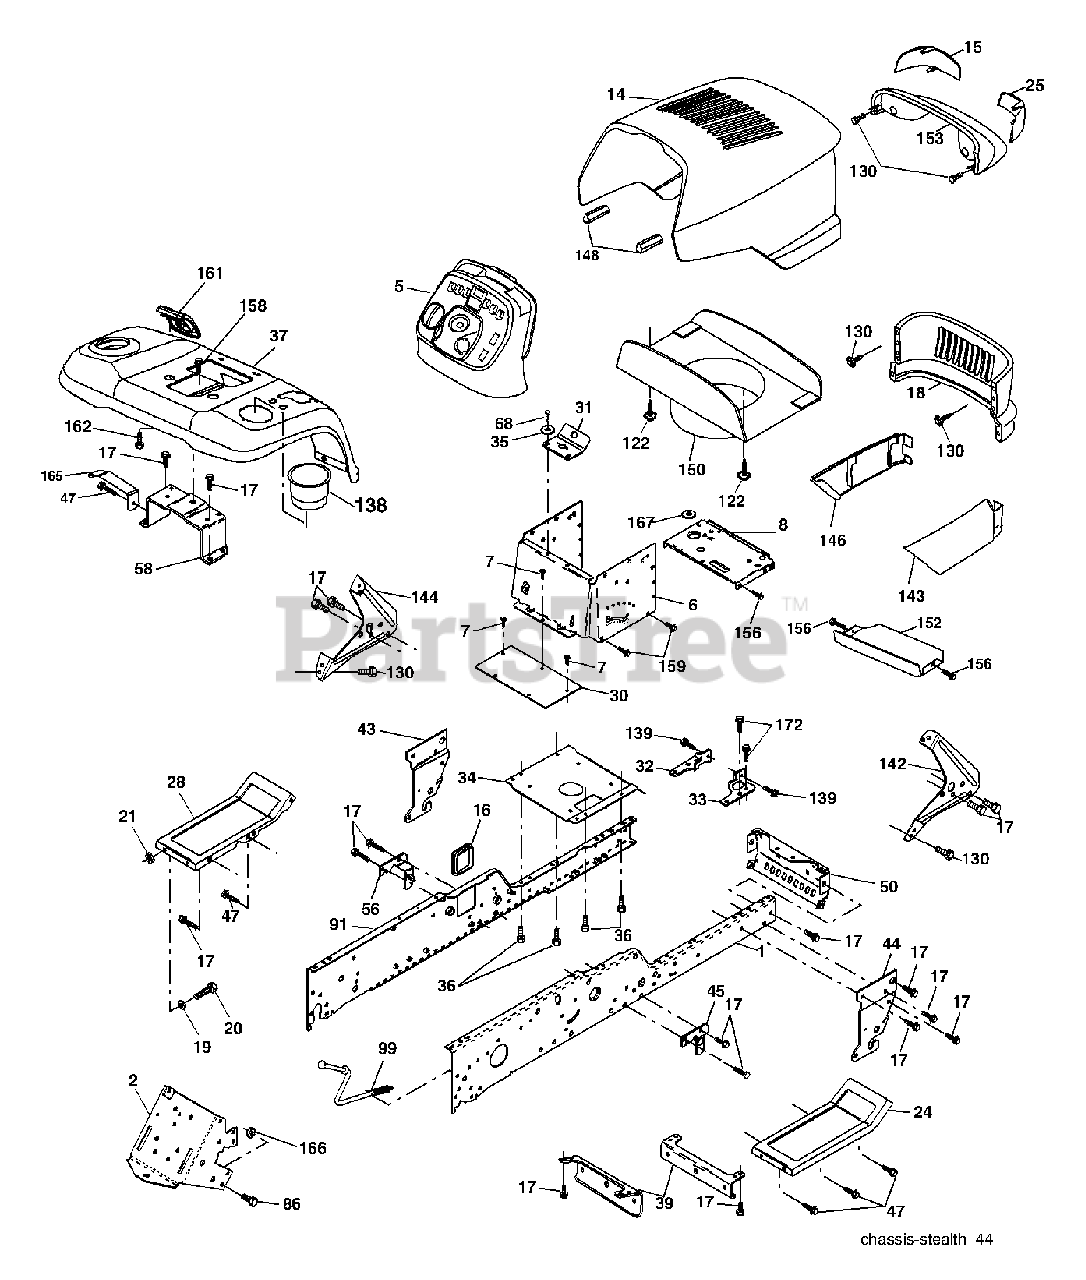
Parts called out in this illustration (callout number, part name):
1	Rail, Kit RH
2	Drawbar, Gt
5	Dash
6	Dash, 1PCS, Lower
7	Screw, Thd Cut 1/4-20 x 1/2
8	Support, Battery
14	Hood Asm., Pnt
15	Lens LH
16	Cover, Access
17	Screw, 3/8-16 x 3/4
19	Washer 13/32 x 13/16 x 12 Ga.
20	Bolt, Fin Hex 3/8-16 x 1
21	Nut, Crownlock 3/8-16
24	Footrest, RH
25	Lens RH
28	Footrest, LH
31	Bracket Supt 1-pc Vgt Steering
32	Bracket, Frame Pivot Lh
33	Bracket, Frame Pivot Rh
34	Plate Asm Engine Chassis
35	Washer 11/32 x 11/16 x 16 Ga.
36	Screw 5/16-18 x 3/4
37	Fender, Pnt.
39	Bracket, Axle Front
43	Bracket, Spnsn Front Lh
44	Bracket, Spnsn Front Rh
45	Bracket, Susp Arm
47	Screw Thdrol 3/8-16 x 1/2
50	Bracket, Chassis Front
56	Bracket Asm Susp Chassis RH
58	Bracket Asm., Fender
68	Screw, 5/16-18 x 1/2
86	Bolt, Fin Hex 7/16-14 unc
91	Rail, Kit Lh
99	Rod Asm. Bypass
122	Screw Hex WSHD 8-18 x 7/8
130	Screw 10 x 3/4 Single Lead-Hex
138	Cupholder
139	Bolt Shoulder 5/16-18
142	Bracket Dash Stealth RH
143	Skirt Grille RH
144	Bracket Dash Stealth LH
146	Skirt Grille LH
148	Extrusion Bumper
150	Duct Heat Hood
152	Shield, Browning
153	Lightbox Asm.
156	Screw 5/16-18 x 3/4
158	Screw 3/8-16 x 1/2
159	Screw Hexwsh Thdr. 3/8-16 x 3/4
161	Cosole Fuel Window
162	Screw 1/4-1/2 Unc
165	Bracket Support Tank
166	Nut, Lock Hex 7/16-14 unc
167	Bushing Snap Nylon 1.250
172	Screw 3/8-16 x .875
